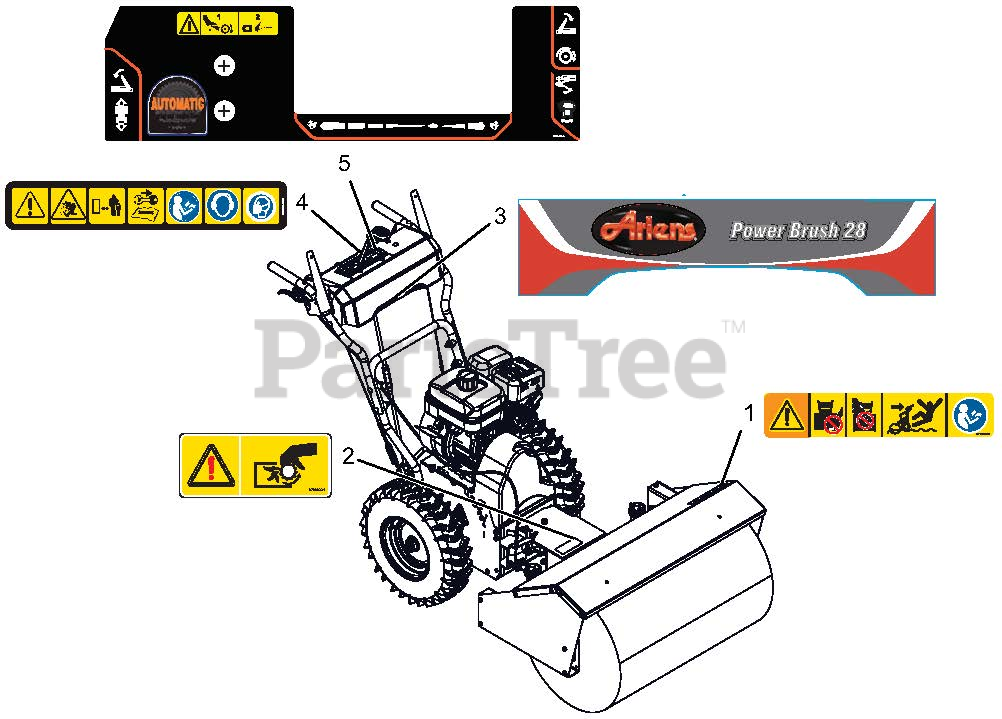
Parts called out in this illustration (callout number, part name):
1	DECAL, DANGER -POWER BRUSH-CE
2	DECAL, PTO WARNING
3	DECAL, POWER BRUSH 28", ARIENS
4	DECAL, SAFETY, DASH, BRUSH
5	DECAL,CONTROL,SMALL BRUSH
